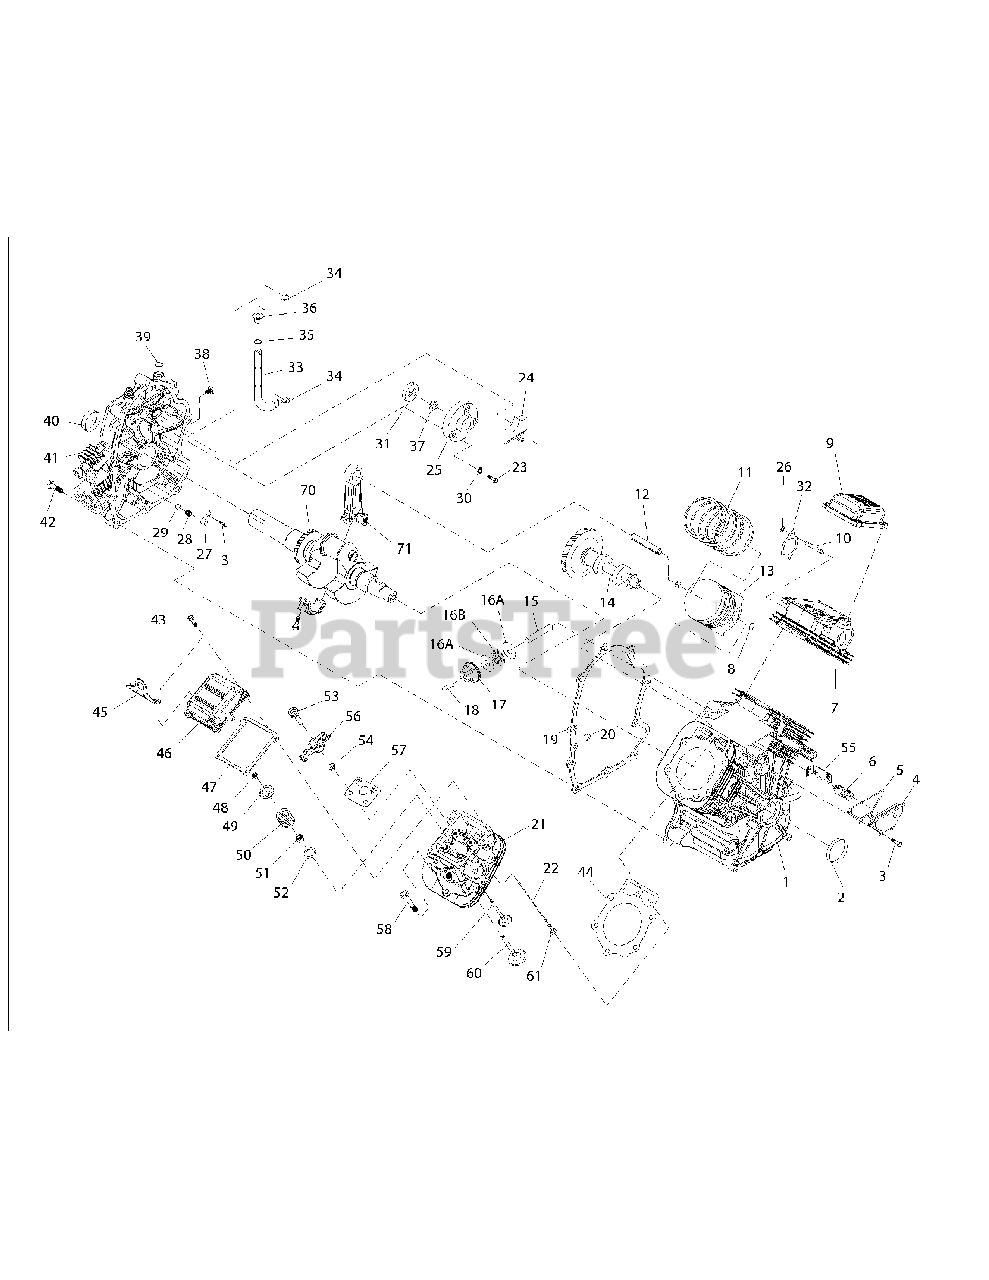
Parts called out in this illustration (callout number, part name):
1	ASSY,CRANKCASE VS W/SLEEVE
2	SEAL, 38 I.D. CRANKSHAFT
3	SCREW, TAPTITE M6-1.0 X 12 YC
4	ASSEMBLY, BREATHER
5	GASKET, BREATHER COVER
6	SEPARATOR, OIL BREATHER
7	ASSEMBLY, HEAD #1
8	RETAINER, PISTON PIN 20
9	ROCKER, COVER NO OIL FILL
10	STUD M8-1.25/10MM X 30 G5 ZINC
11	SET, PISTON RING 90MM
12	PIN PISTON 20 DIA X 48 LONG
13	PISTON, 8.5:1 90MM DIA (LOW COMP.)
14	ASSEMBLY, CAMSHAFT & GEAR
15	SHAFT, GOVERNOR
16A	ROLLER BEARING, GOVERNOR PLATE
16B	ROLLER BEARING, GOVERNOR
17	ASSEMBLY,GOVERNOR GEAR
18	SPOOL, GOVERNOR MACHINED
19	GASKET, CRANK CASE
20	SEAL, OIL PASSAGE
21	ASSEMBLY, HEAD #2
22	PUSHROD, 147
23	SCREW SHC M6-1.0 X 30 G8.8
24	SCREEN, OIL PICKUP
25	COVER, GEROTOR
26	NUT LOCK FL M8-1.25
27	COVER, OIL RELIEF
28	SPRING, OIL RELIEF
29	BALL, 1/2D OIL RELIEF
30	WASHER, LOCK RIB M6
31	GEROTOR, OUTER
32	GASKET, EXHAUST
33	ARM, GOVERNOR
34	E-RING, GOVERNOR ARM
35	THRUST WASHER, GOVERNOR
36	BUSHING, GOVERNOR LOWER
37	GEROTOR, INNER
38	PLUG, DRAIN
39	SEAL, GOVERNOR SHAFT
40	SEAL, 42 I.D. CRANKSHAFT
41	ASSEMBLY, SUMP WITH SLEEVE
42	SCREW, HHFC M10-1.5 X 55
43	SCREW HHFC M6-1.0 X 25
44	GASKET, HEAD
45	HOOK, LIFTING
46	ASSEMBLY, ROCKER COVER W/
47	GASKET, VALVE COVER
48	KEEPER, VALVE SPRING
49	RETAINER, VALVE SPRING
50	SPRING, VALVE
51	SEAL, VALVE STEM D7
52	WASHER, VALVE SPRING
53	STUD, ROCKER ARM PIVOT
54	NUT, HEX M8-1.0 G8 YEL CHR
55	SCREEN C'CASE BREATHER
56	ROCKER ARM
57	PLATE, PUSH ROD GUIDE
58	SCREW HHFC M8-1.25 X 65
59	VALVE, EXHAUST
60	VALVE, INTAKE
61	TAPPET, SOLID
70	ASSY,CRANKSHAFT & GEAR 100MM
